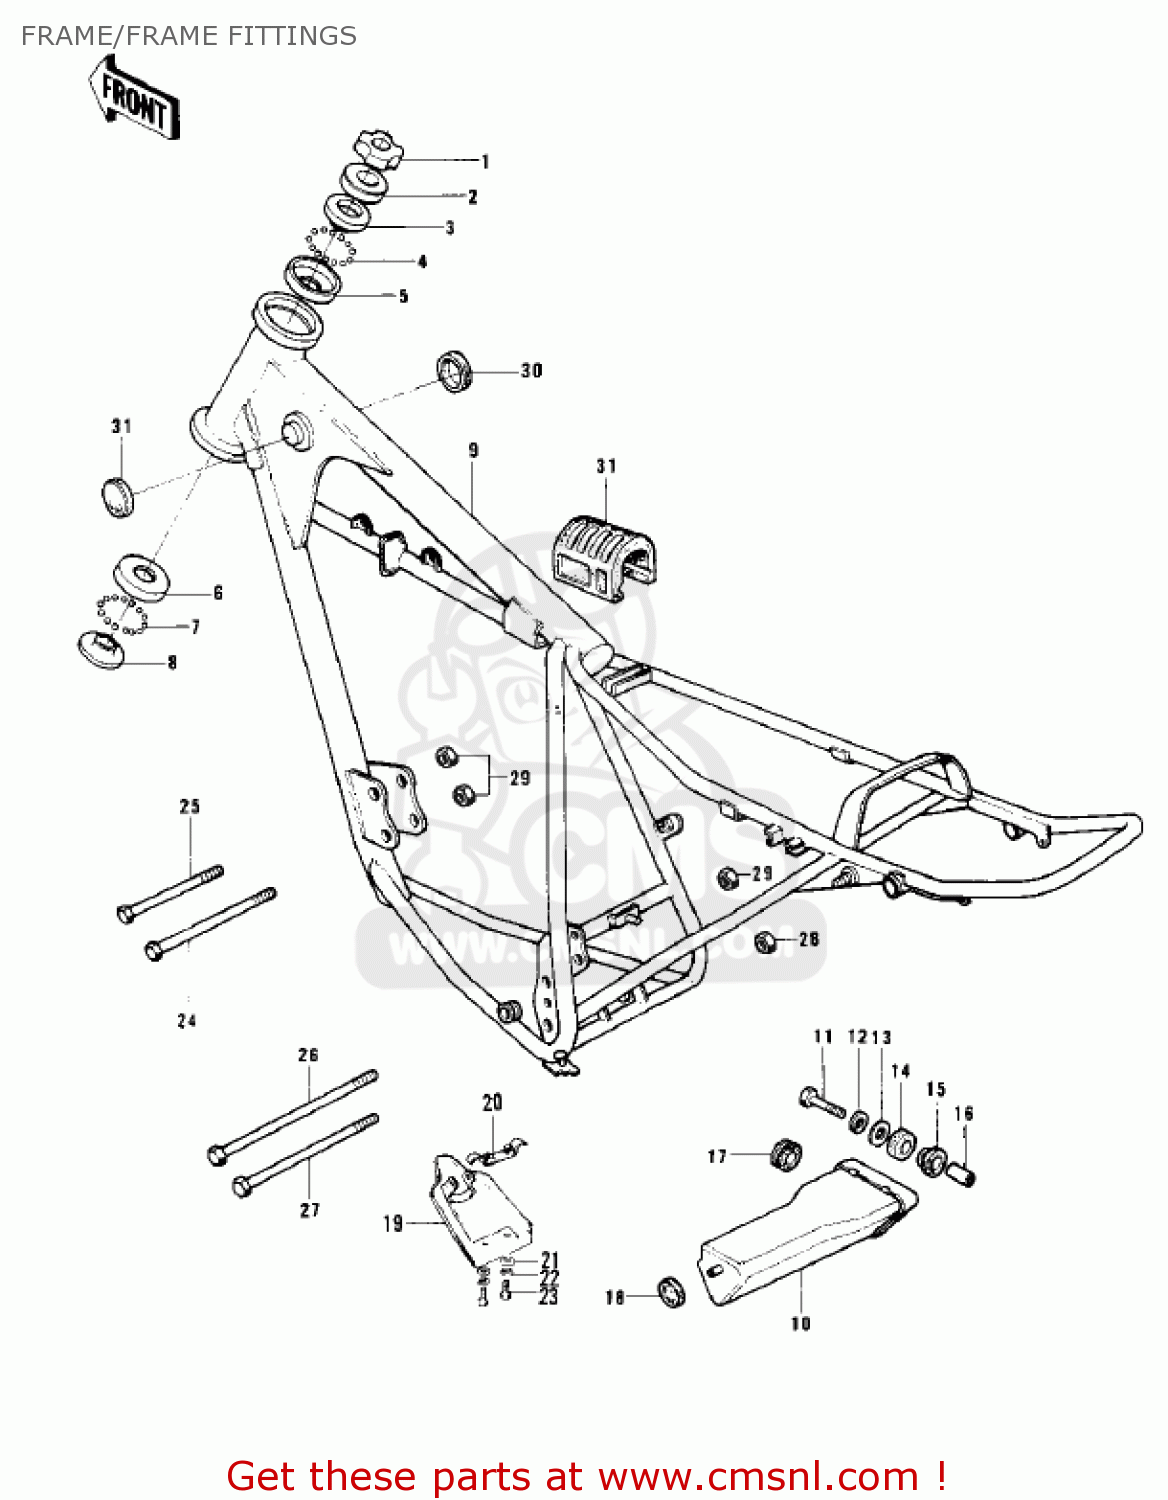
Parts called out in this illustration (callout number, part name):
1	NUT,STEERING LOCK,25M
2	CAP,STEERING STEM
3	RACE,STEERING STEM BE
4	BALL-STEEL,3/16
5	RACE,STRG STM
6	CONE-STERNG BERG LOW
7	BALL-STEEL,1/4
8	RACE-STEERING BEARING
9	FRAME
10	CASE,TOOL
11	BOLT-UPSET,6X25
12	WASHER-SPRING,6MM
13	WASHER-PLAIN,7MM
14	DAMPER,FEMALE
15	DAMPER,MALE
16	COLLAR-REAR FENDER
17	DAMPER,OIL TANK
18	DAMPER
19	GUARD,ENGINE
20	BRACKET,ENGINE GUARD
21	WASHER,6.5X20X1.6
22	WASHER-SPRING,6MM
23	BOLT UPSET,6X16
24	BOLT,FLANGED,8X70
25	BOLT,HEX HEAD,8X65
26	BOLT,HEX HEAD,10X130
27	BOLT,FLANGED,10X115
28	NUT,10MM
29	NUT,LOCK,8MM
30	DAMPER RUBBER-FL TANK
31	DAMPER,FUEL TANK
